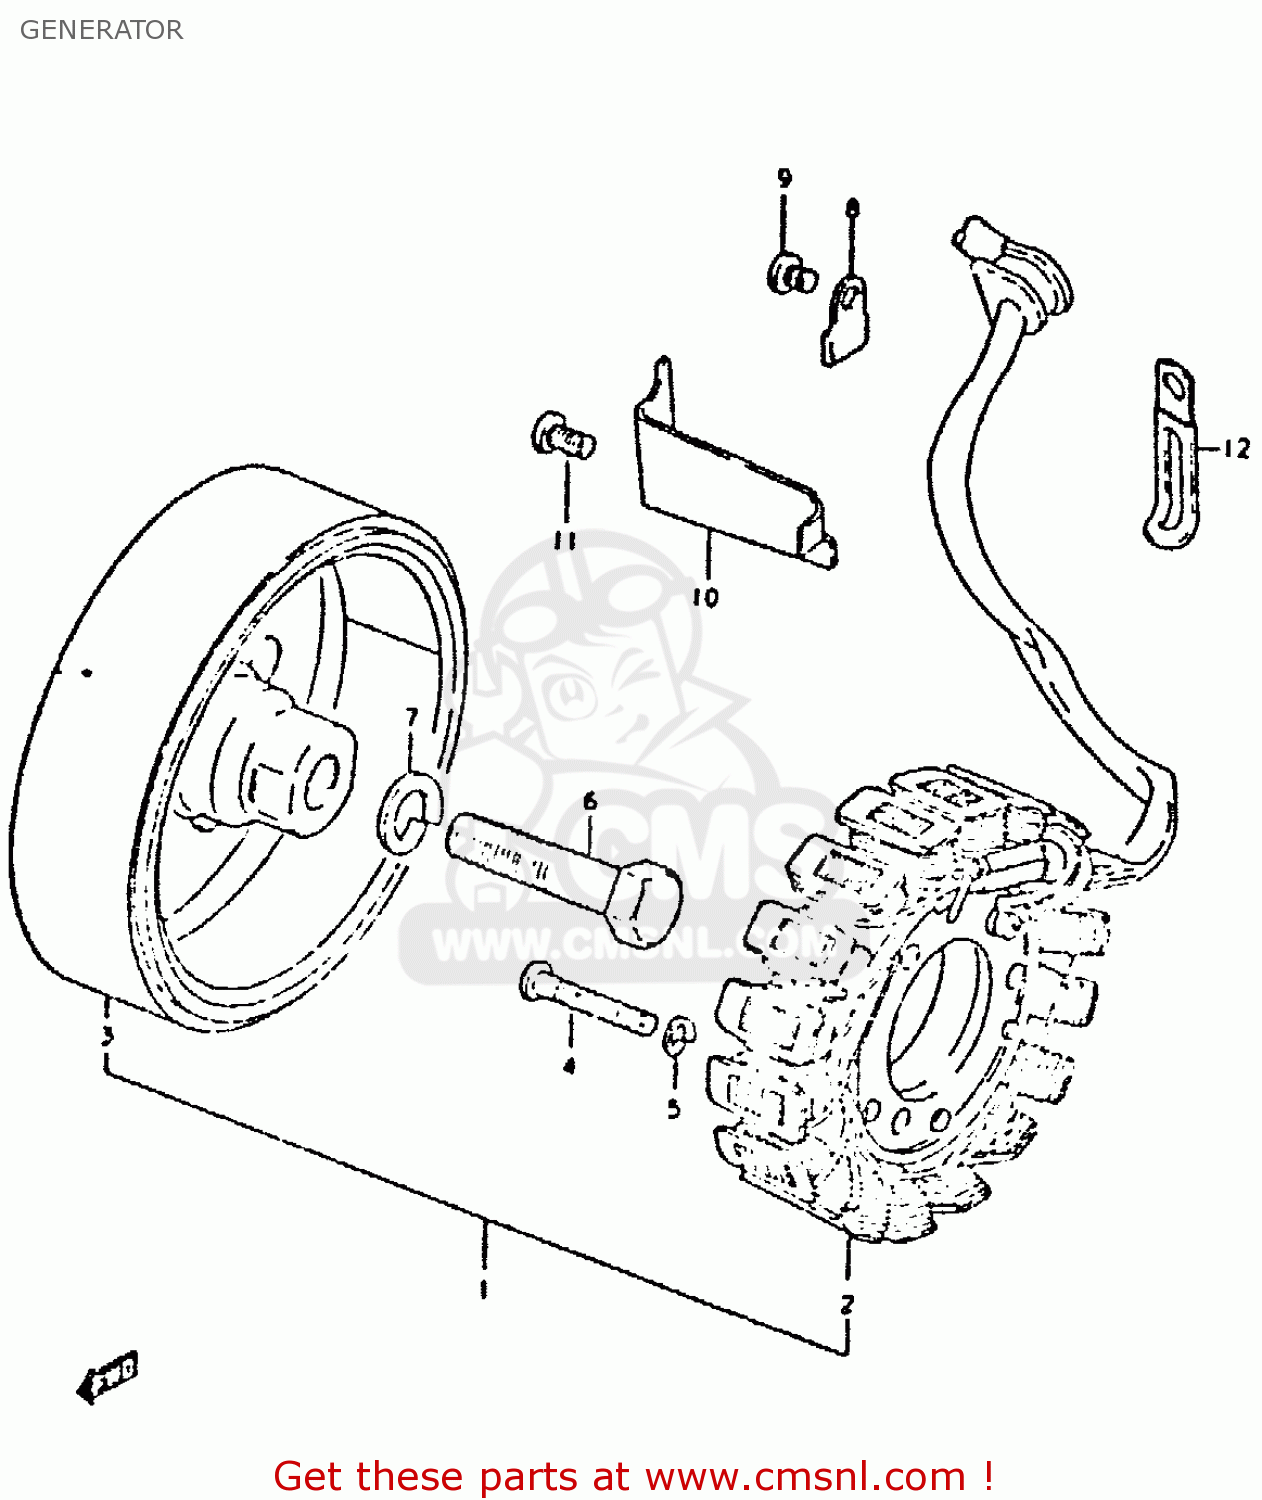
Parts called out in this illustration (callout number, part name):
1	GENERATOR ASSEMBLY
2	STATOR ASSEMBLY
3	ROTOR ASSEMBLY
4	SCREW
5	LOCK WASHER
6	BOLT 12X45
7	WASHER,LOCK 12
8	CLAMP,GENERATOR LEAD WIRE
9	SCREW
10	CLAMP,GENERATOR LEAD WIRE
11	SCREW
12	CLAMP L:35
